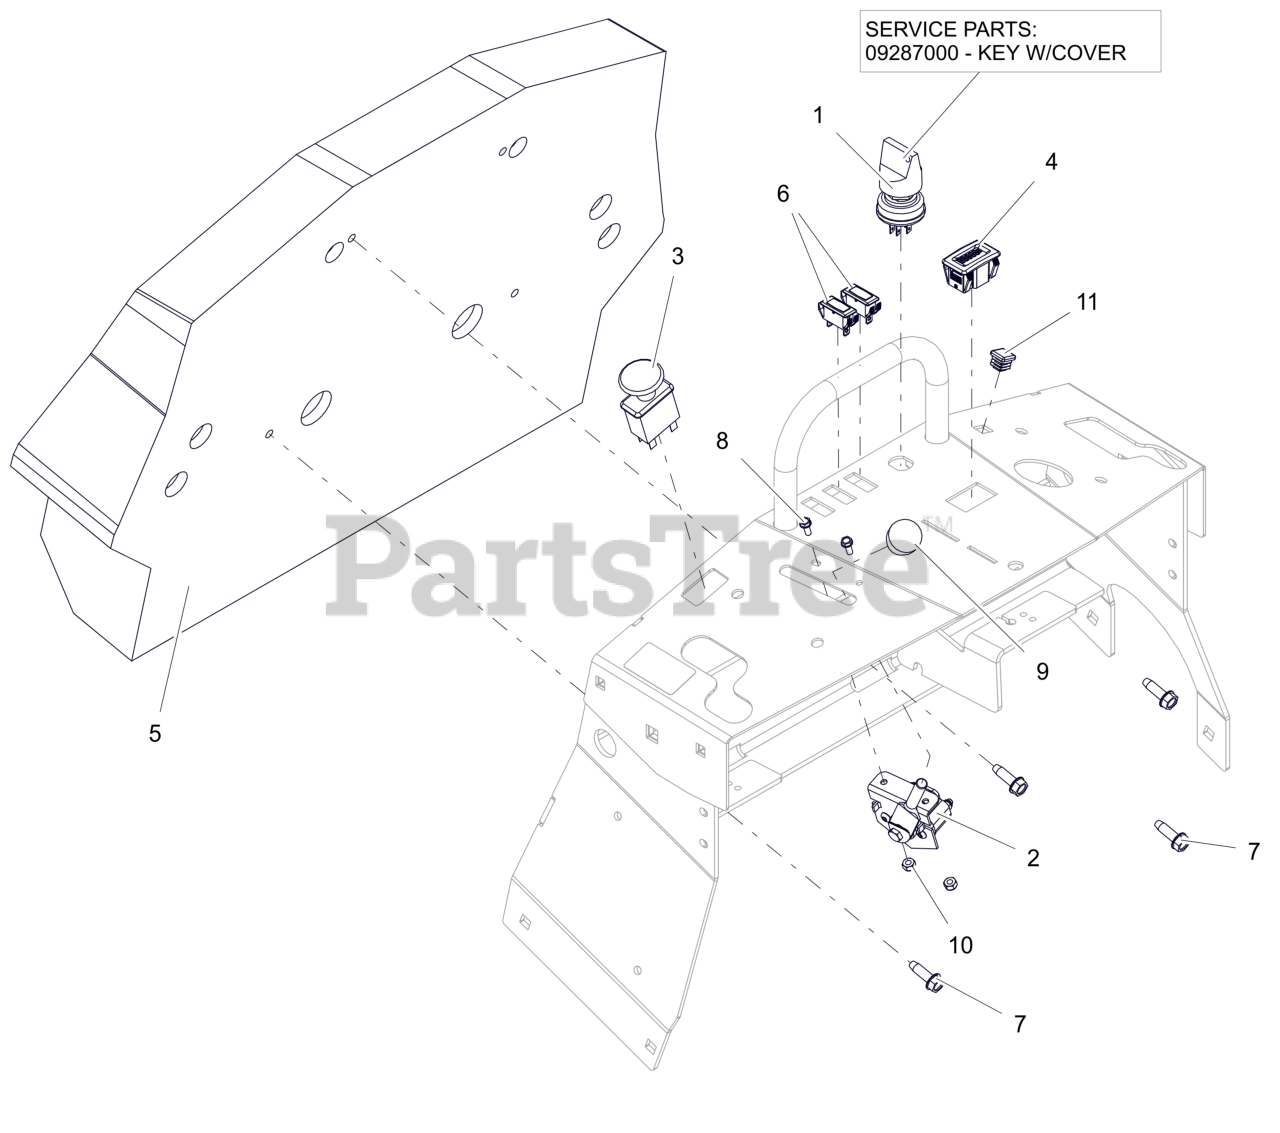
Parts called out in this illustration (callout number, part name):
1	SWITCH, IGNITION
1	KEY, W/ SHIELD
2	CONTROL, ELECTRONIC THROTTLE
3	SWITCH, CLUTCH
4	HOUR METER
5	PAD, OPERATOR - PROSTANCE
6	LIGHT, INDICATOR (RED)
7	SCR-TAP .312-18X1.00 HWH ZCC
8	BLT, HWH #10-24X.50 ZCC
9	KNOB-CONTROL-BLACK .38-16X.50
10	NUT-LK-NYL #10-24 G2 ZCC
11	PLUG, 5/8" SQ BLACK (14-20GA)
